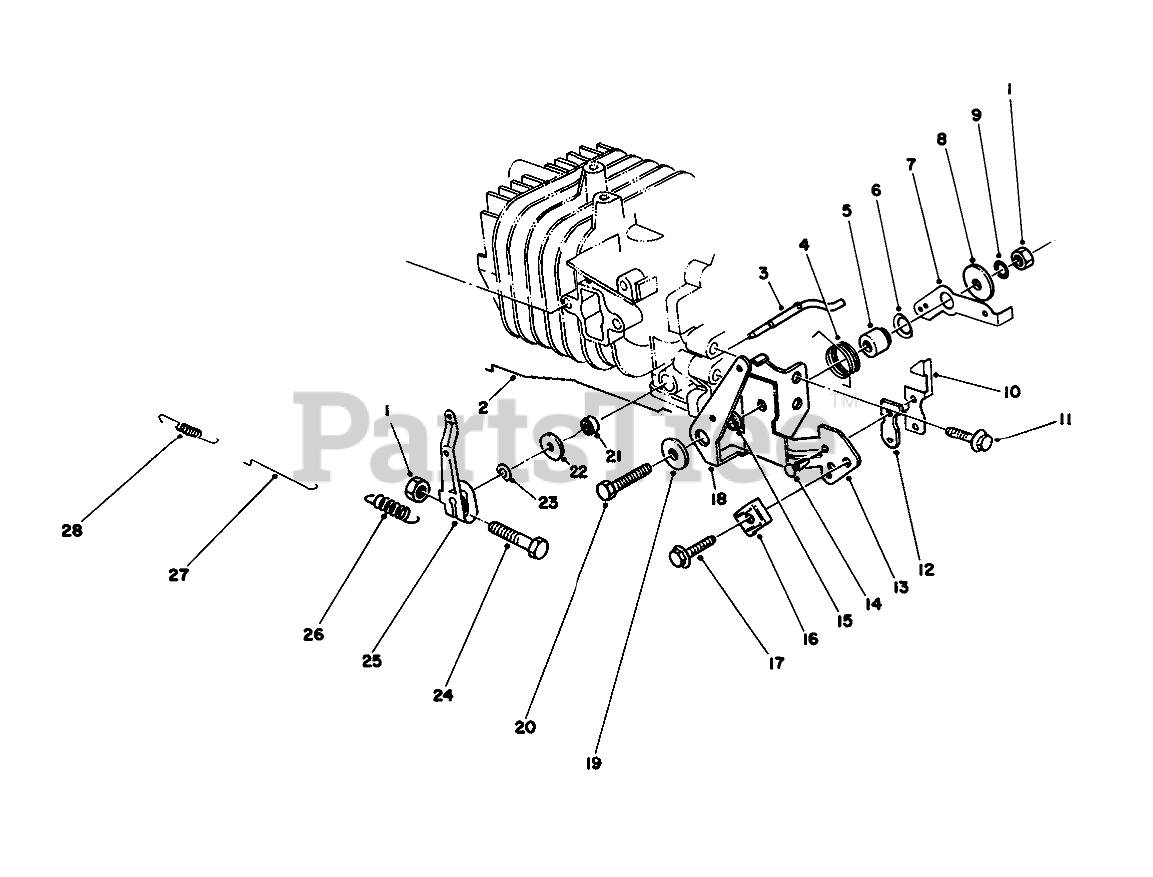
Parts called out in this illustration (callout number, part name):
2	CHOKE ROD
3	Shaft-Govemor
4	SPRING-CHOKE LEVER
5	Gov Lever Spacer
6	Washer-Gov. Spring Lever
7	GOV SPRING LEVER
8	WASHER
9	LOCKWASHER
10	TERMINAL-KILL SWITCH
12	INSULATOR-KILL SWITCH
13	BRACKET-THROTTLE, CONTROL
14	KILL SWITCH RIVET
15	SPACER-CHOKE LEVER
16	CLAMP
18	LEVER-CONTROL, CHOKE
19	WASHER
21	SEAL-OIL
22	WASHER
23	E-RING
25	Lever-Throttle Control
26	GOVERNOR SPRING
27	ROD-CARBURETOR
28	SPRING
